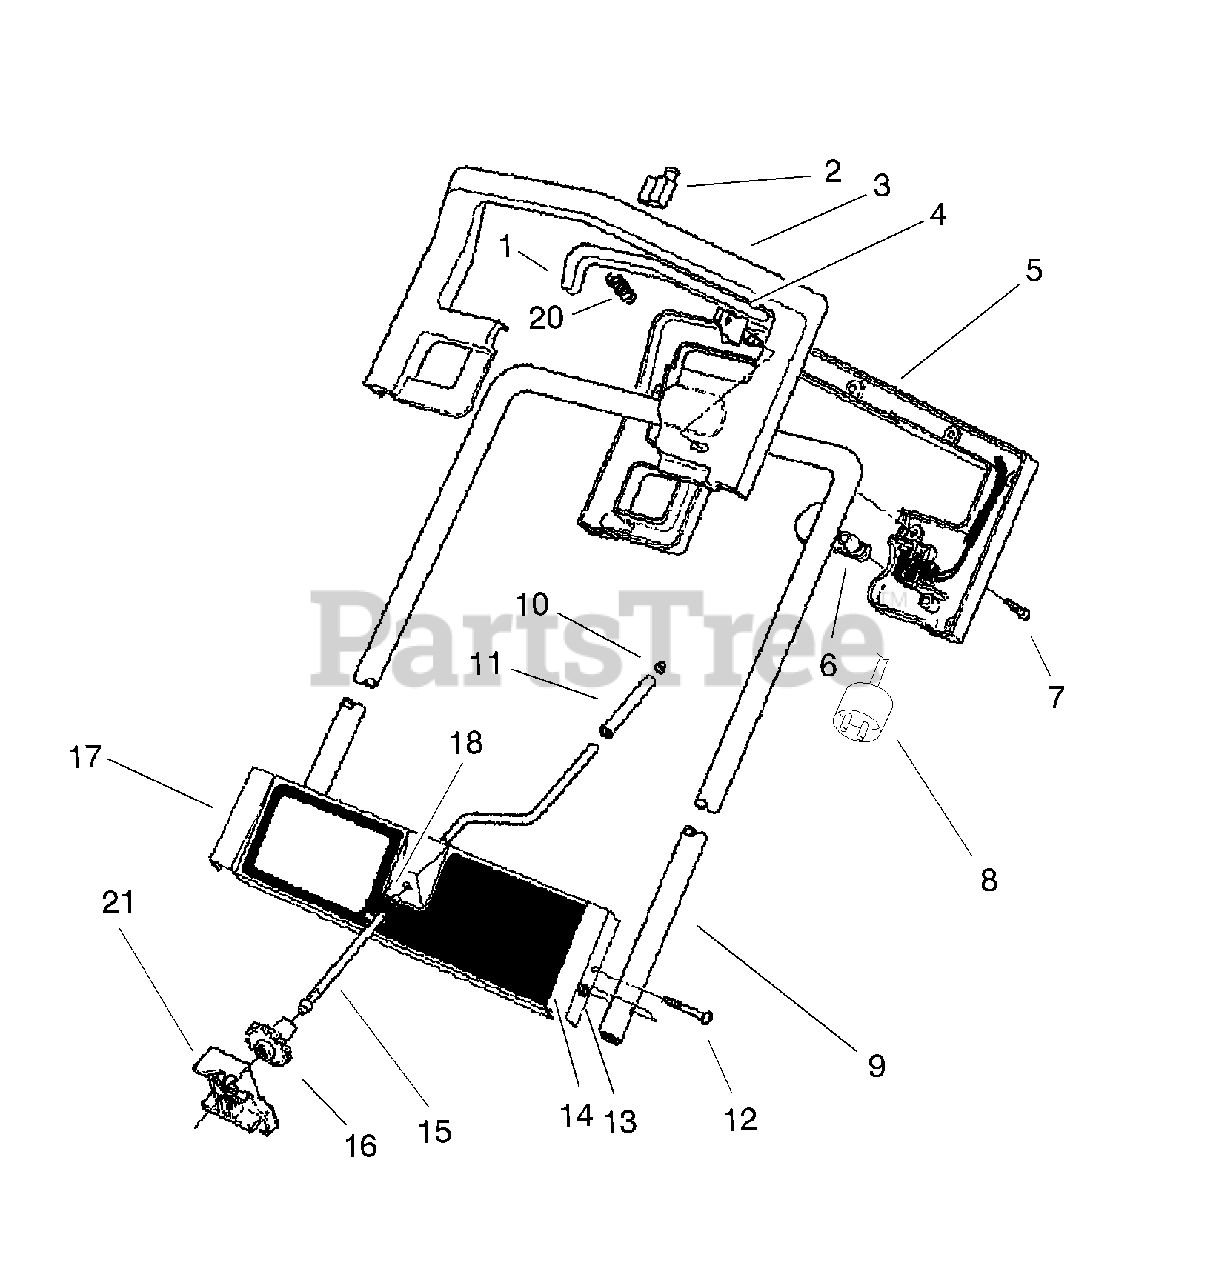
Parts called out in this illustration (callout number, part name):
1	Bar-Switch
2	Switch-Defond
3	Handle - Upper Control
5	Handle-Control, Lower
6	Tab-Lock
7	SCREW-PPH
8	Cord - Supply
9	Tube - Upper Handle
10	PUSHNUT-CAP, WASHER
11	Sleeve-Crank, Chute
12	Screw-HH
13	NUT-LOCK, NI
14	Decal - Escutcheon
15	Rod-Crank, Chute
16	Gear-Crank, Chute
17	Plate - Escutcheon
18	Bushing-Nyliner
21	Brake-Gear
